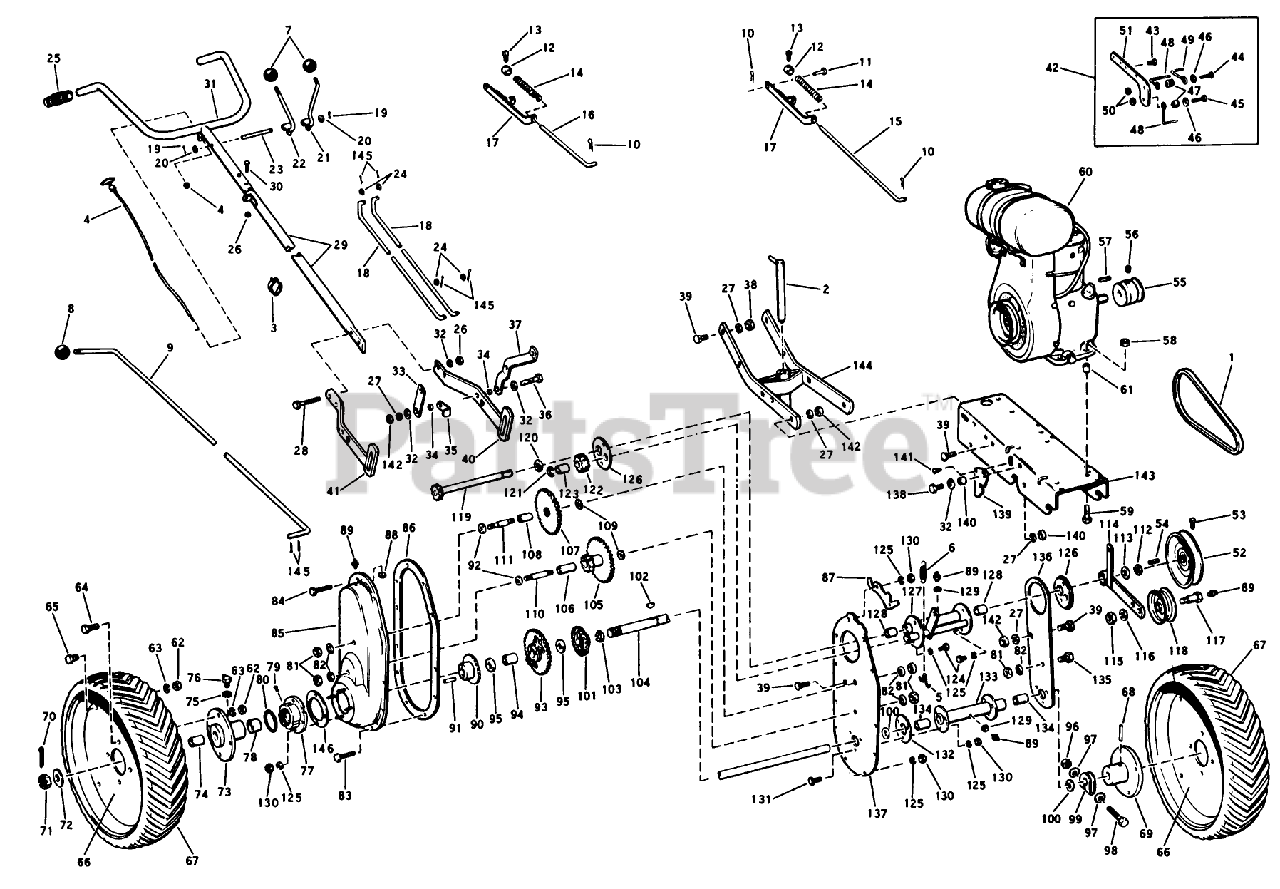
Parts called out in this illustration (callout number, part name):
1	Lockwasher
2	Hitch Pin
5	Bushing
13	Set Screw
16	Trans. Control Spring Rod
17	Spring Bracket
18	TINE LH
19	Cotter Pin
21	Control Handle, L.H.
22	Control Handle, R.H.
28	Hex Capscrew
29	Lower Tube
33	Shifting Lever
36	Hex Capscrew 3/8-16 x 1-1/2 Lg.
38	Hex Nut 3/8-16
39	Carr. Bolt 3/8-16 x 1-1/2 Lg.
40	Handlebar Brkt., L.H.
41	HandlebarBrkt., R.H.
42	Belt Guide Assembly
44	Hex Capscrew 5/16 18 x 1-1/4 Lg.
45	Hex Capscrew 5/16 18 x 1-1/8 Lg.
46	BAR-LIFT LINK *R
52	Pulley Assembly
53	Set Screw
56	Set Screw
58	Nut and Washer
59	Hex Capscrew
62	Hex Nut 5/16-18
64	Hex Capscrew 5/16-18 x 1 Lg.
65	Hex Capscrew 5/16-18 x 5/8 Lg.
69	GEAR 24T
70	Cotter Pin
71	Hex Slotted Nut
73	Right Wheel Hub Assy.
74	Bushing
75	Lockwasher
76	Grease Fimng
77	Flange Bushing Assy.
78	Bushing
79	Grease Fitting
80	Oil Seal
81	Hex Jam Nut 7/16 x 14
83	Hex Capscrew 1/4-20 x 1/2 Lg.
84	Capscrew
85	Gearcase Cover
88	Hex Jam Nut
89	Grease Fitting
91	Rear Wheel
93	Final Drive Gear Dif. Pinion Assembly
94	Bushing
95	Thrust Washer
96	Hex Nut
98	Hex Capscrew
105	Second Intermediate Gear and Pinion Assembly
107	First Inter. Gear Pinion Assy.
108	Bushing (Oilite)
111	First Intermediate Shaft
112	Retaining Ring
114	Idler Pulley Lever
115	Hex Jam Nut
118	Idler Pulley
119	Input Gear
121	Retaining Ring
122	Idler Pinion Assembly
123	Bushing
124	Capscrew
125	Lockwasher 1/4
127	Input Tube Idler Shaft Assy.
129	Lift Bar
130	Hex Nut
131	ASSEMBLY MUFFLER
133	Axle Tube Assembly
134	Bushing
135	Capscrew 7/16-14 x 3/4 Lg.
136	Left Support Plate
137	Back Plate
141	Drive Screw #10 x 3/8 Lg.
145	BUMPER-RUBBER
146	Flange Bushing Gasket
